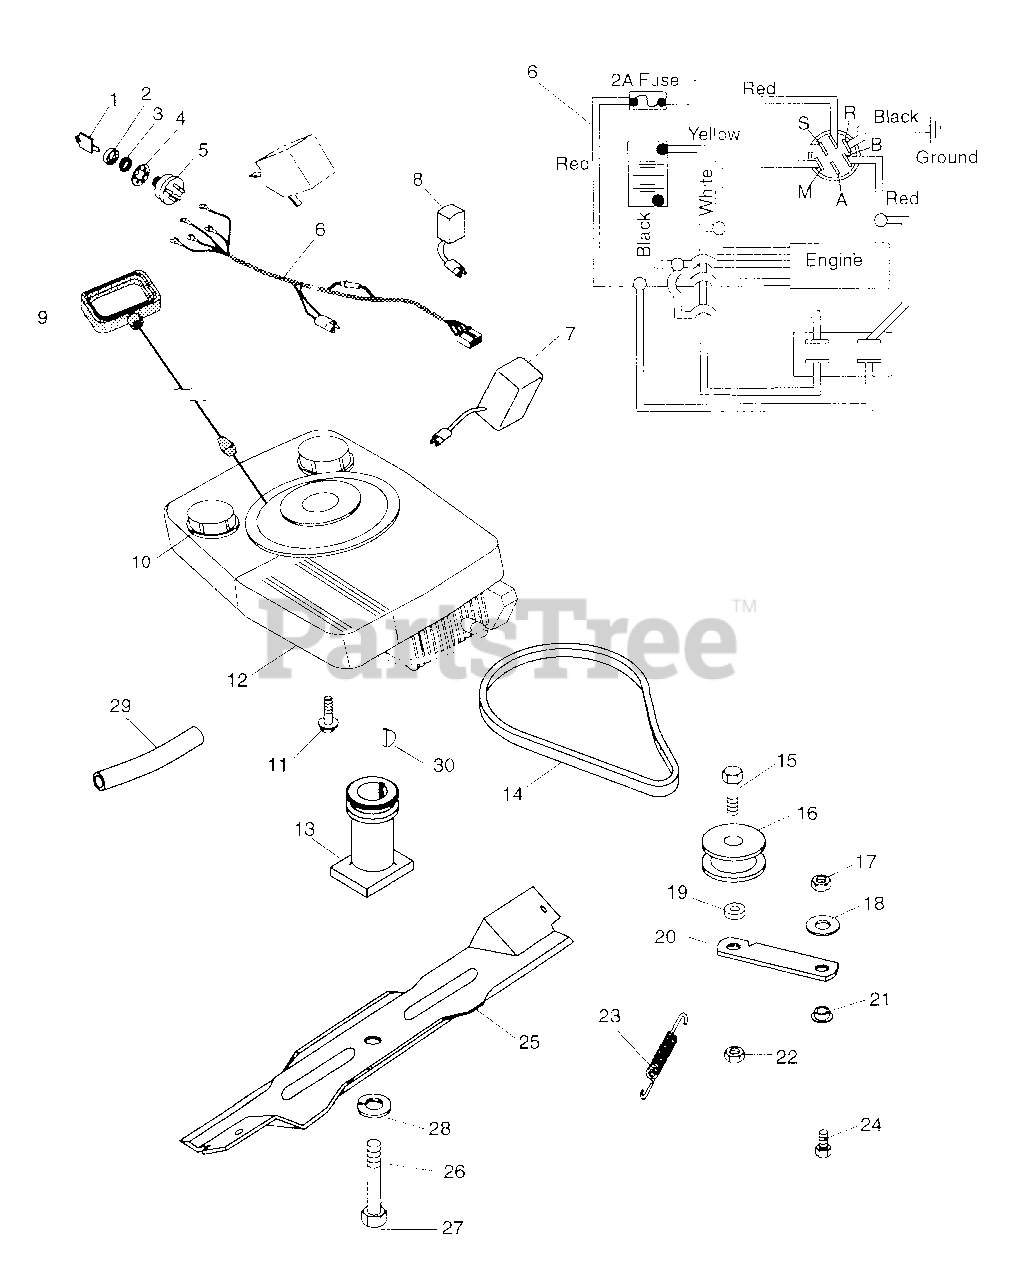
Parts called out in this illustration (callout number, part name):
1	KEY -W/CAP
2	CAP - IGNITION SWITCH
3	NUT-PANEL .625-32 GRECO
4	WSHR-LK-INT .625X.045 PL
5	KEY SWITCH
6	WIRE HARNESS
7	BATTERY
8	BATTERY CHARGER
9	HANDLE, RECOIL START
10	FUEL CAP
11	SCR-TAP .375-16X1.0 HWH PL TR
12	ENG, 5 HP KAW (W/PRESS LUBE)
12	ENGINE TEC. 5.0HP. CENTURA
12	ENGINE TEC. 5.5HP. CENTURA
12	ENGINE B&S 5.5HP. DIAMOND PLUS
12	ENGINE TEC 6.0HP RECOIL VECTOR
12	ENGINE TEC 6.0HP ELEC. RECOIL
12	ENGINE B&S 5.5HP DMND PLS 8195
12	ENGINE TEC 6HP REC VECTOR 8195
12	ENGINE TEC 6HP ELE VECTOR 8195
12	ENGINE B/S 5HP QUANTUM XTE
12	ENGINE TEC. 5HP RECOIL 2 CYCLE
12	ENGINE TEC 5.0HP CENTURA CARB
12	ENGINE TEC 5.5HP CENTURA CARB
13	PLZ READ SERVICE LETTER #L-429
13	BLADE ADAPTER 1.00 DIA SPLINE
14	V-BELT, 3L-COGGED
15	BLT-HEX .44-14X1.25 PL GR2
16	IDLER-FLAT 1.75 X .47
17	NUT-LK .312-18 GR A PL
18	WSHR-FL-STL .323X.625X.062 PL
19	SPACER .52 X .45 X .34
20	IDLER ARM
21	BSHG-FLG .325X.501X.250X1.120
22	NUT-LK .437-14 GR A PL
23	SG-TENS .043X.44X3.31 WLD 5.8
24	BLT-HEX .31-18X.75 PL GR2
25	21" MOWER BLADE
25	21IN MULCHING BLADE
26	WSHR-LK .375X.094 MED PL
27	BLT-HEX .38-24X2.00 PL GR5
28	WSHR-HDND-THR .390X1.50X.125PL
29	DRAIN HOSE
30	KEY-WDRF .156X.625X.25 SAE 6
